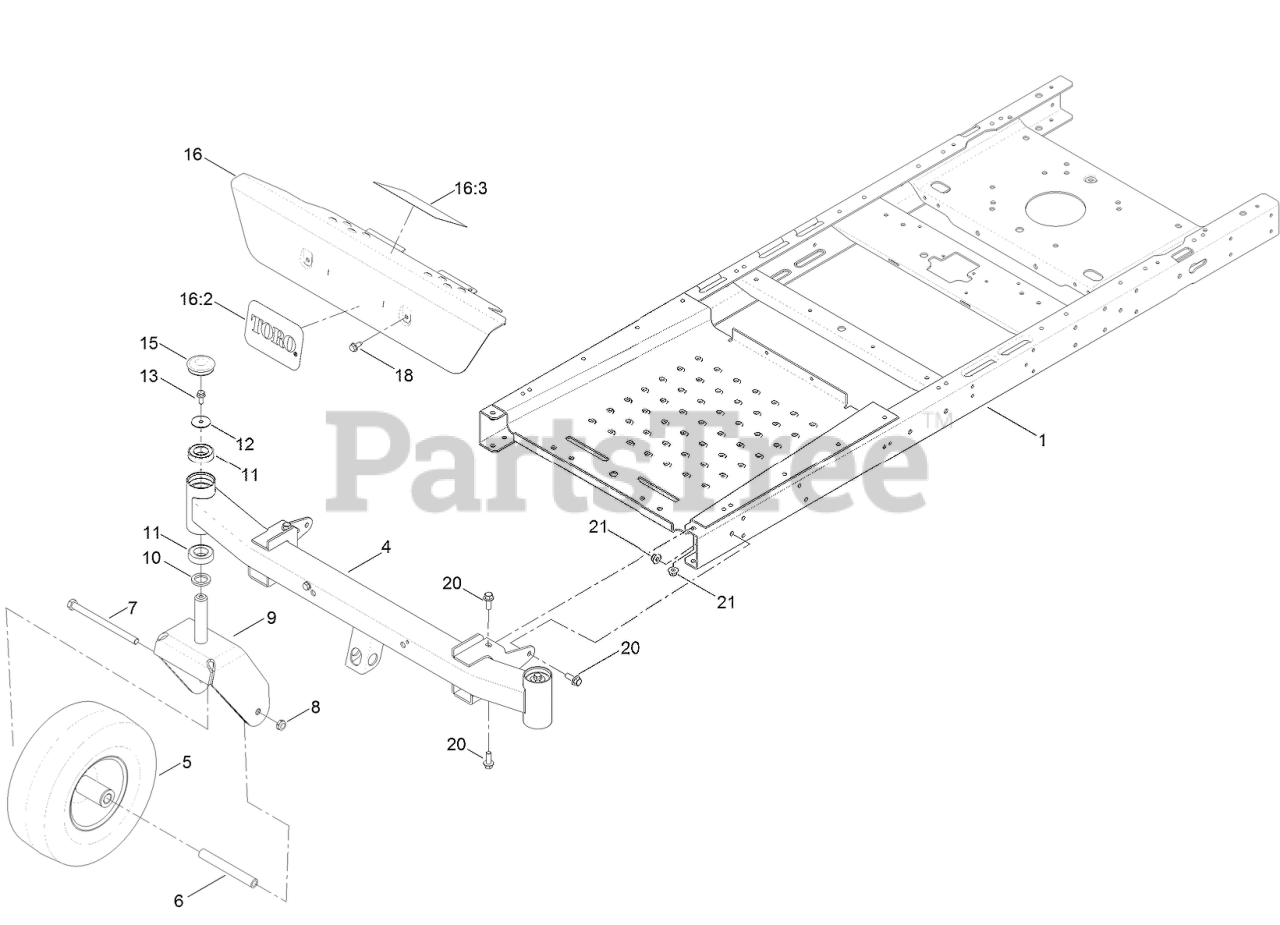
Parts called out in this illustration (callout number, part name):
1	FRAME ASM
4	AXLE ASM
5	13 INCH WHEEL AND TIRE ASM
6	SPANNER
7	SCREW-HH
8	NUT-LOCK, NI
9	FORK-CASTER
10	WASHER-THRUST
11	BEARING-BALL
12	WASHER-FLAT
13	SCREW-HHF
15	CAP-GREASE
16	Footrest ASM
16:2	DECAL
16:3	DECAL-DANGER
18	SCREW-HWHTF
20	SCREW-HHF
21	NUT-HF, NI
